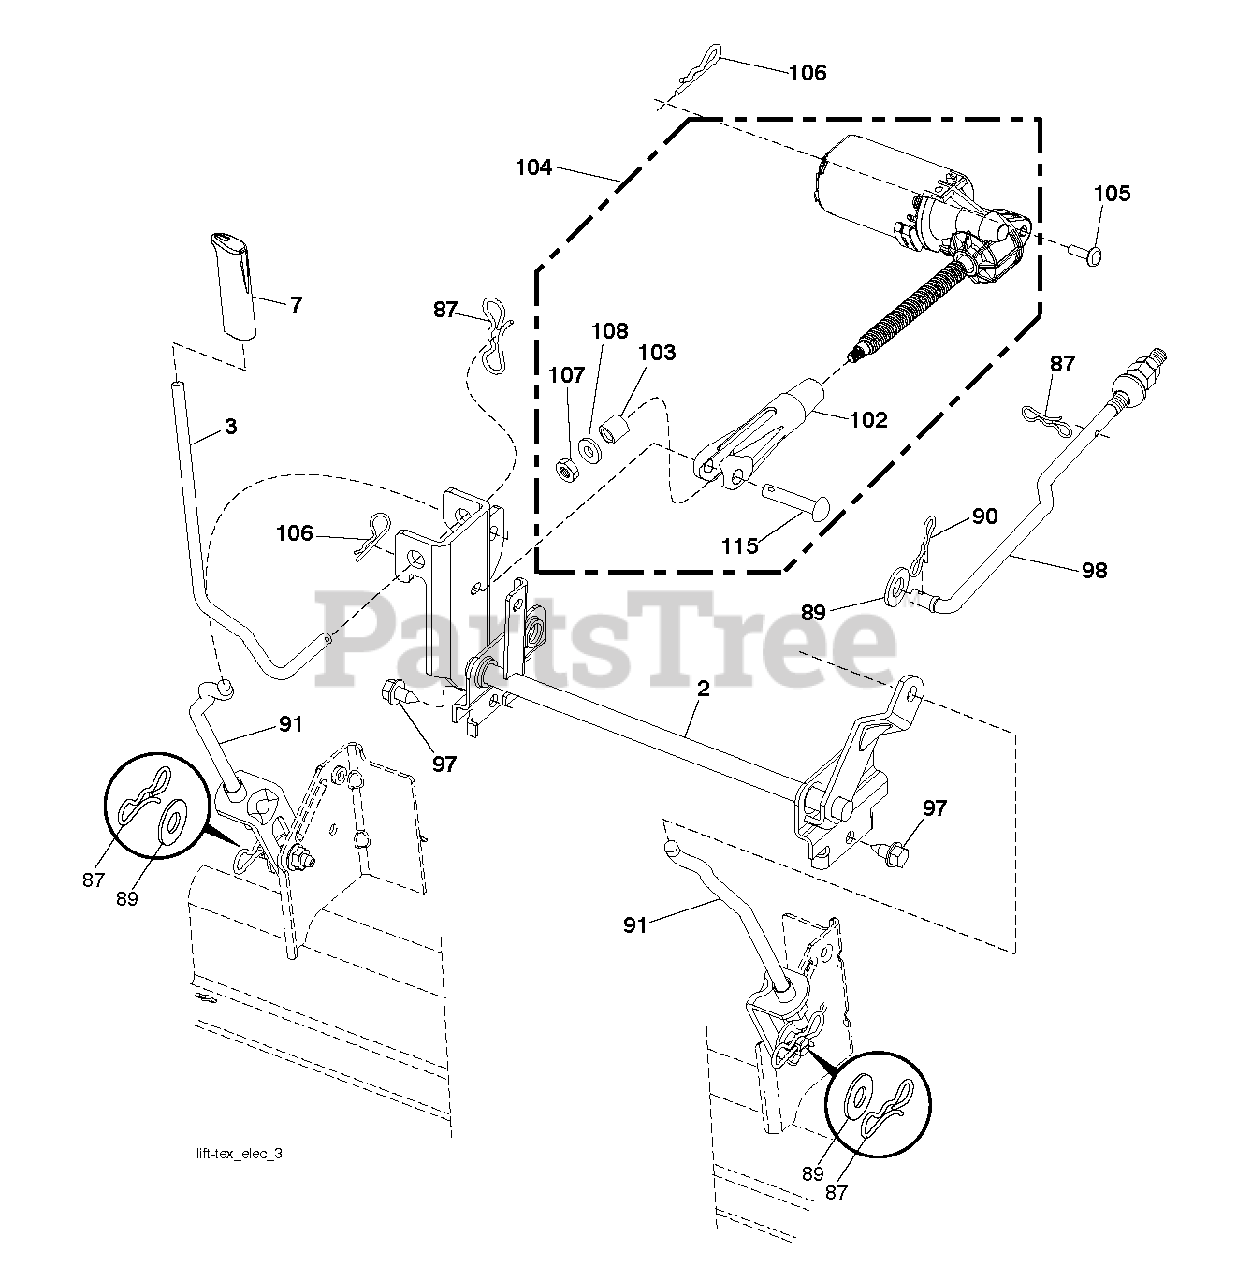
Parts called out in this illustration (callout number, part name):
2	SHAFT.ASM.CROSS.LIFT
3	ROD INDICATOR
87	PIN.COTTER.7/16.BOW TI
89	WASHER.CLEAR.ZINC
90	PIN.COTTER.5/16.BOW TI
91	LINK.ASM.LIFT.54"TG
97	SCREW, 3/8-16X3/4
98	LINK.ASM.SUSP.FRONT.MWR.10.5
102	CLEVIS.MOTOR.EKLECTRIC
103	SPACER.TUBULAR
104	ACTUATOR.ASM.DECKLIFT.ELECT
105	RIVET,DRILLED
107	NUT.SQ.1/4-20 UNC
115	PIN.CLEVIS.375X2.125
